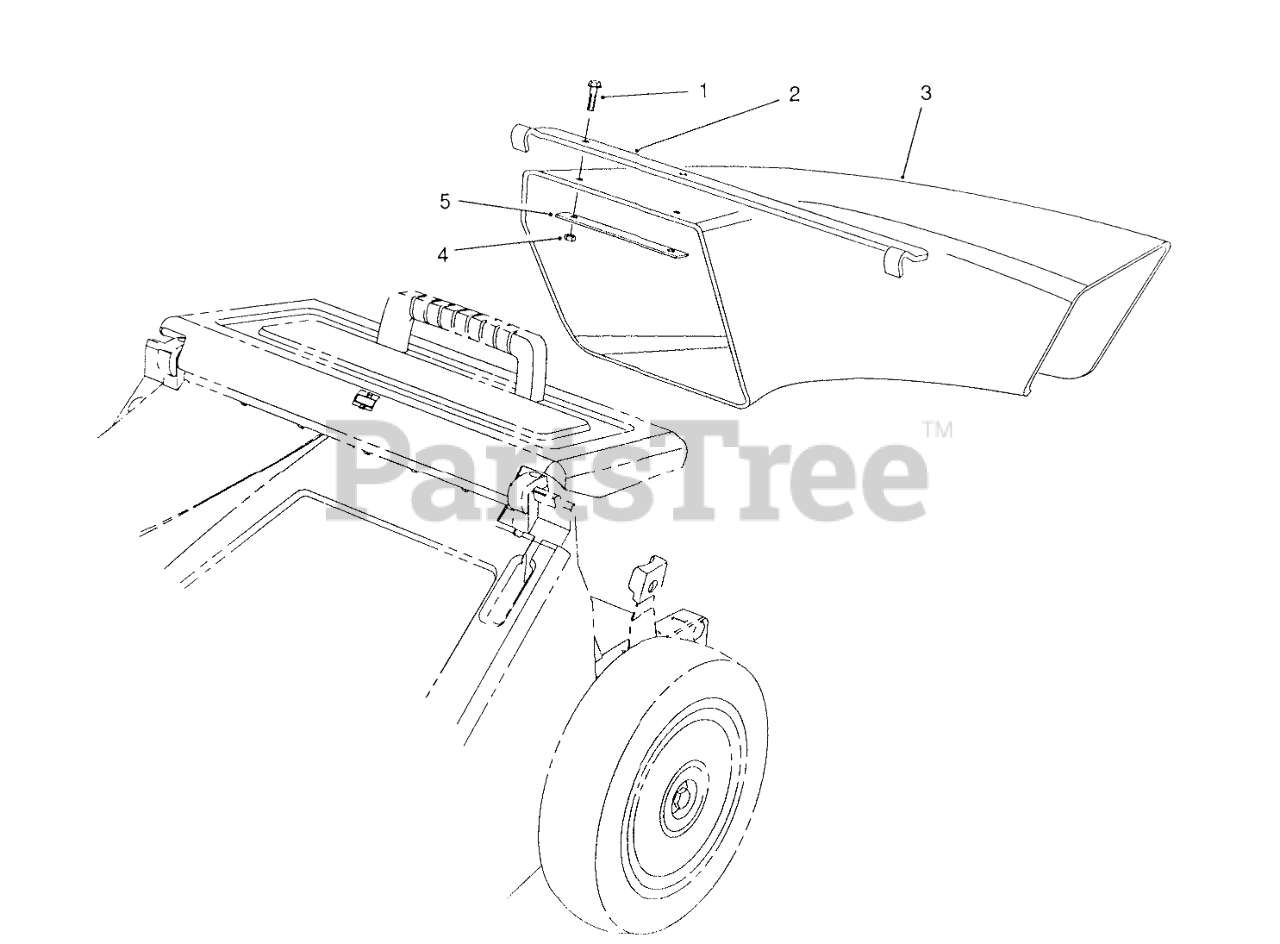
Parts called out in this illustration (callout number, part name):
1	SCREW-HWH
2	CHUTE HANGER BRACKET
3	Chute-Discharge
4	NUT-LOCK, NI
5	STRESS PLATE
